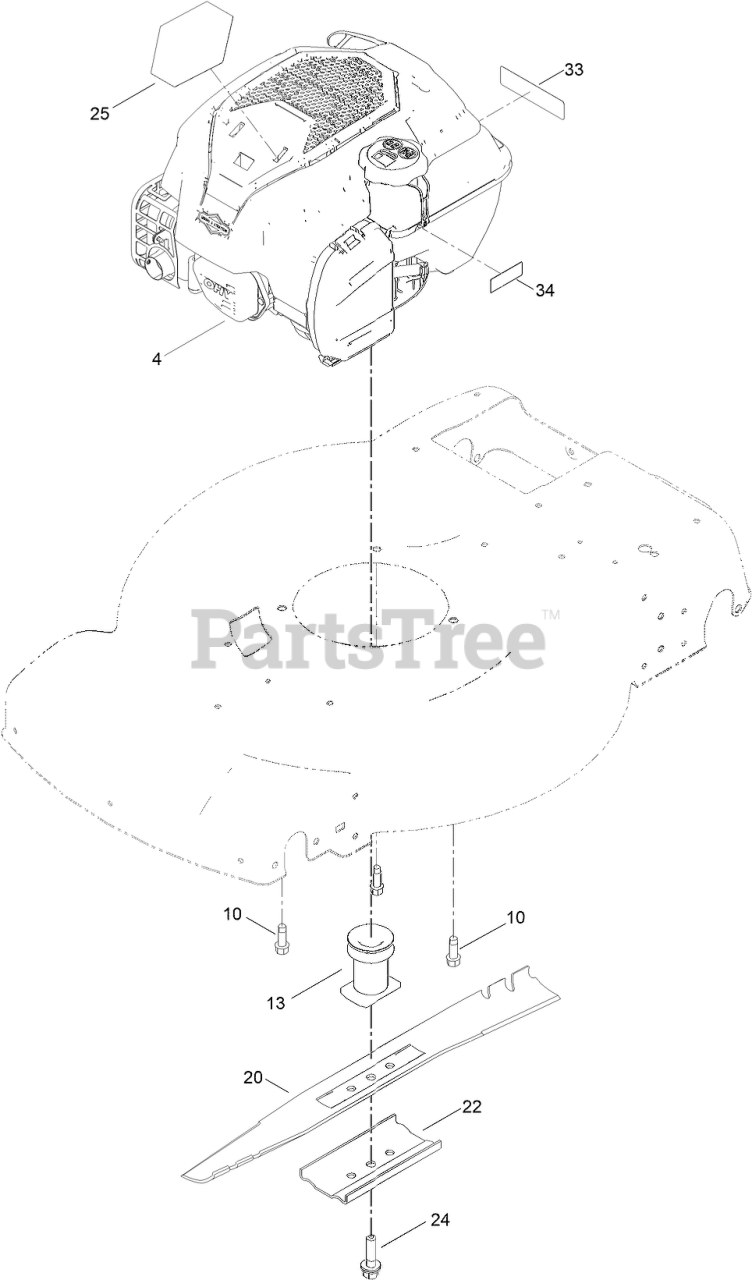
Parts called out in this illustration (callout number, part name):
4	ENGINE-BRIGGS, 625 EXI ZS SS
10	SCREW-THD FORM, HWH
13	DRIVER-BLADE
20	BLADE-22 INCH
22	SUPPORT-BLADE
24	BOLT-BLADE
25	DECAL-BRIGGS 625 EXI SS
33	DECAL-ARRESTOR, SPARK
34	DECAL-LEVEL, FUEL
